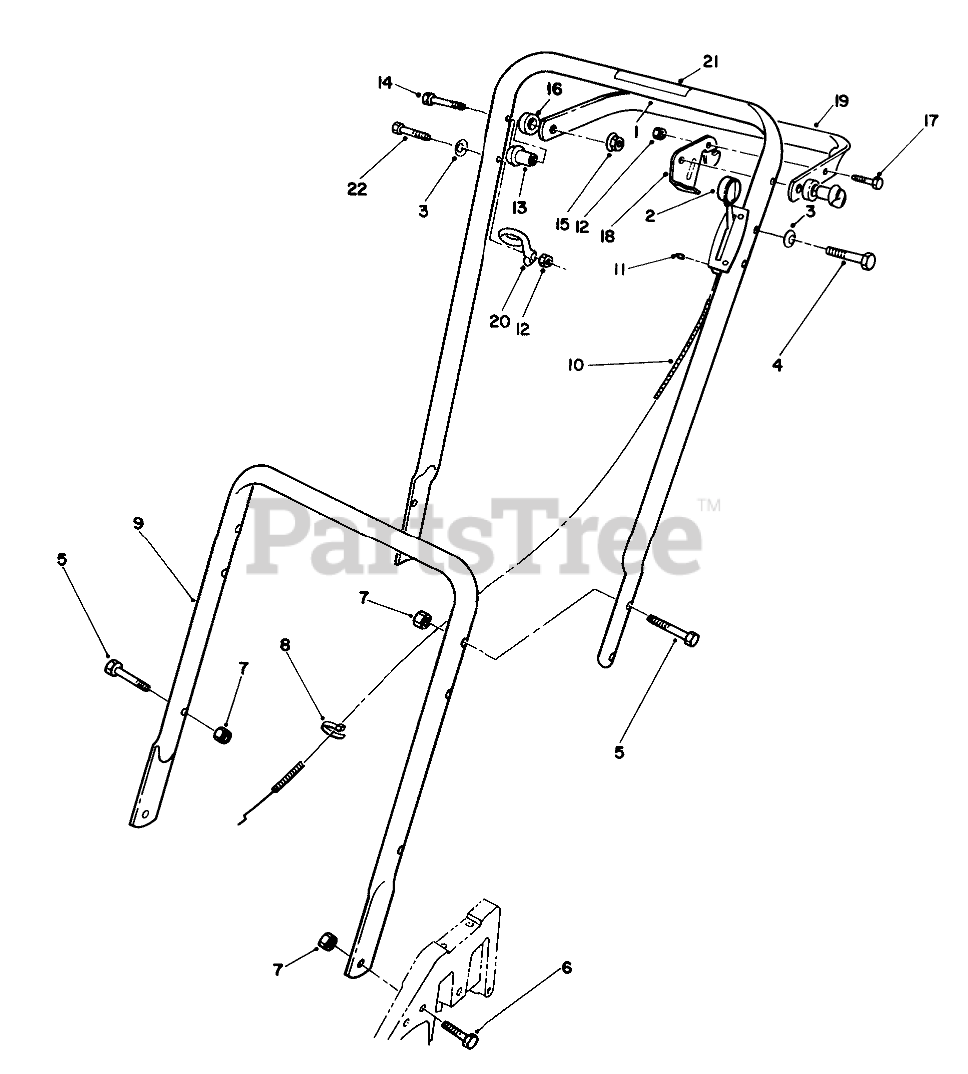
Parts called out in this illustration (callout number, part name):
1	Upper Handle Assembly (Incl. Ref. #21)
2	CONTROL-THROTTLE
3	WASHER
4	SCREW-HH
5	SCREW-HH
6	SCREW-HH
7	NUT-LOCK, NI
8	TIE-CABLE
9	Handle-Lower
10	CABLE-THROTTLE
11	E-RING
12	NUT-LOCK, NI
13	SPACER-SUPPORT
14	SCREW-HH
15	NUT-LOCK, NI
16	SPACER-NYLON
17	SCREW-HH
18	LEVER-CONTROL
19	Bar-Control
20	GUIDE-ROPE
21	WARNING DECAL
22	SCREW-HH
